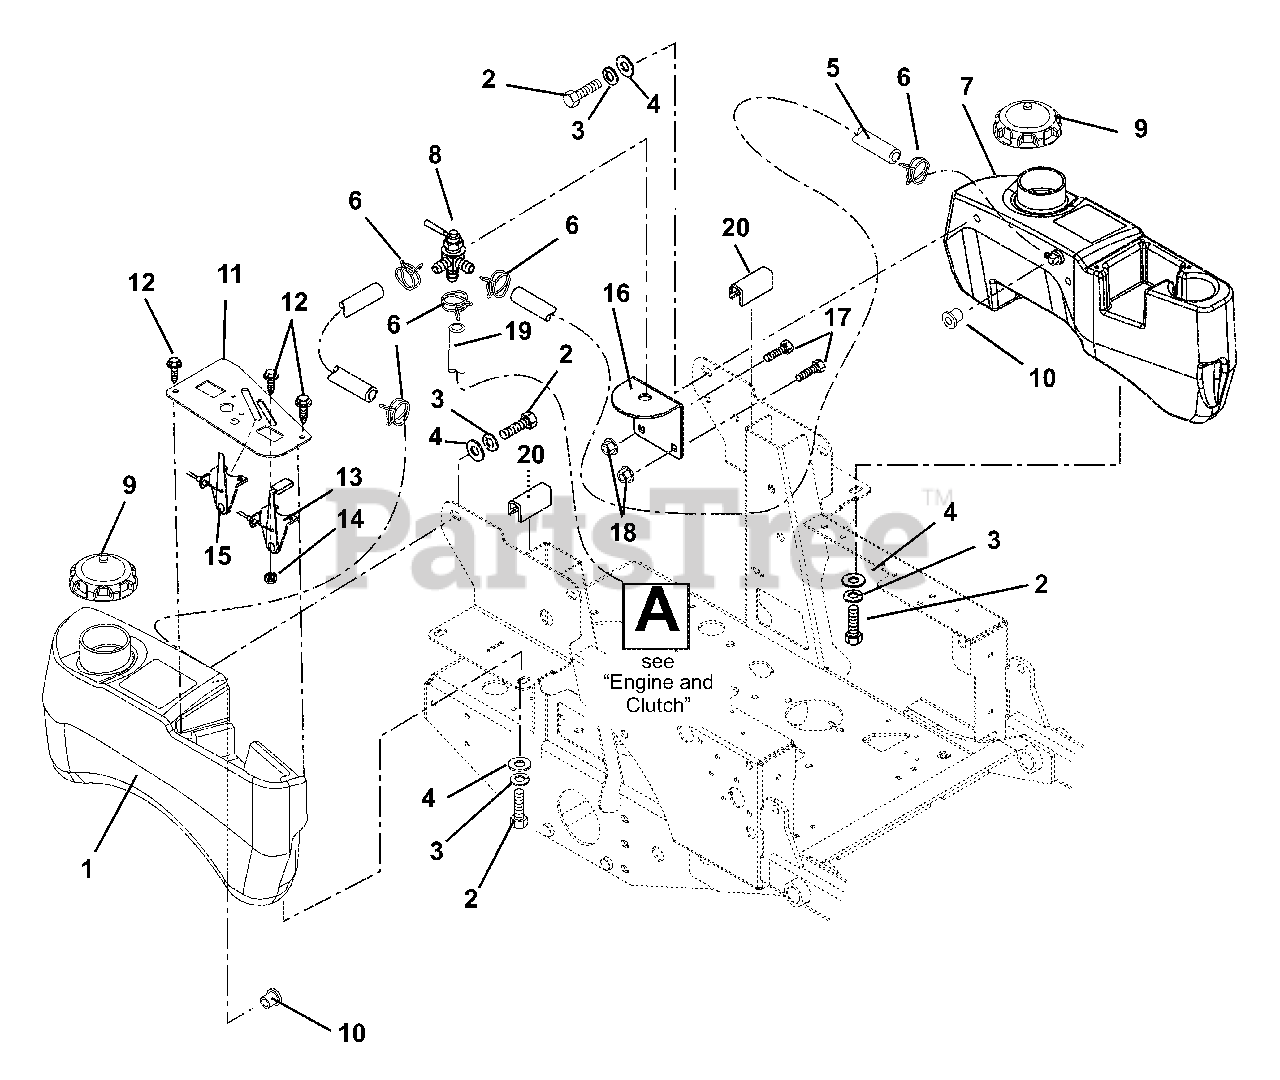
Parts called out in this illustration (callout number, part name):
1	Tank, Gas- Right Hand
2	Bolt, Hex .31-18 x .75 Grade 5
3	Washer, Locking .31 x .078
4	Washer, Flat Steel .38 x .875 x .083
5	Hose, Gas Line 6.25"- .25" I.D.
6	Hose, Clamp
7	Tank, Left Hand Fuel (Eye-Q)
8	Valve, Fuel
9	Cap, Fuel
10	Bushing
11	Panel, Control
12	Screw, Machine 10-24 x .50 Hex Washer Head
13	Cable, Throttle Choke
14	Nut, Locking Nylon 10-24 With Insert
15	Cable, Choke
16	Bracket, Fuel Valve Mounting
17	Bolt, Round Head Square Neck .31-18 x .75 Grade 5
18	Nut, Top Locking Flange .31-18
19	Hose, Gas Line 29"- .25" I.D.
20	Cowl Strip 1.75" Long
